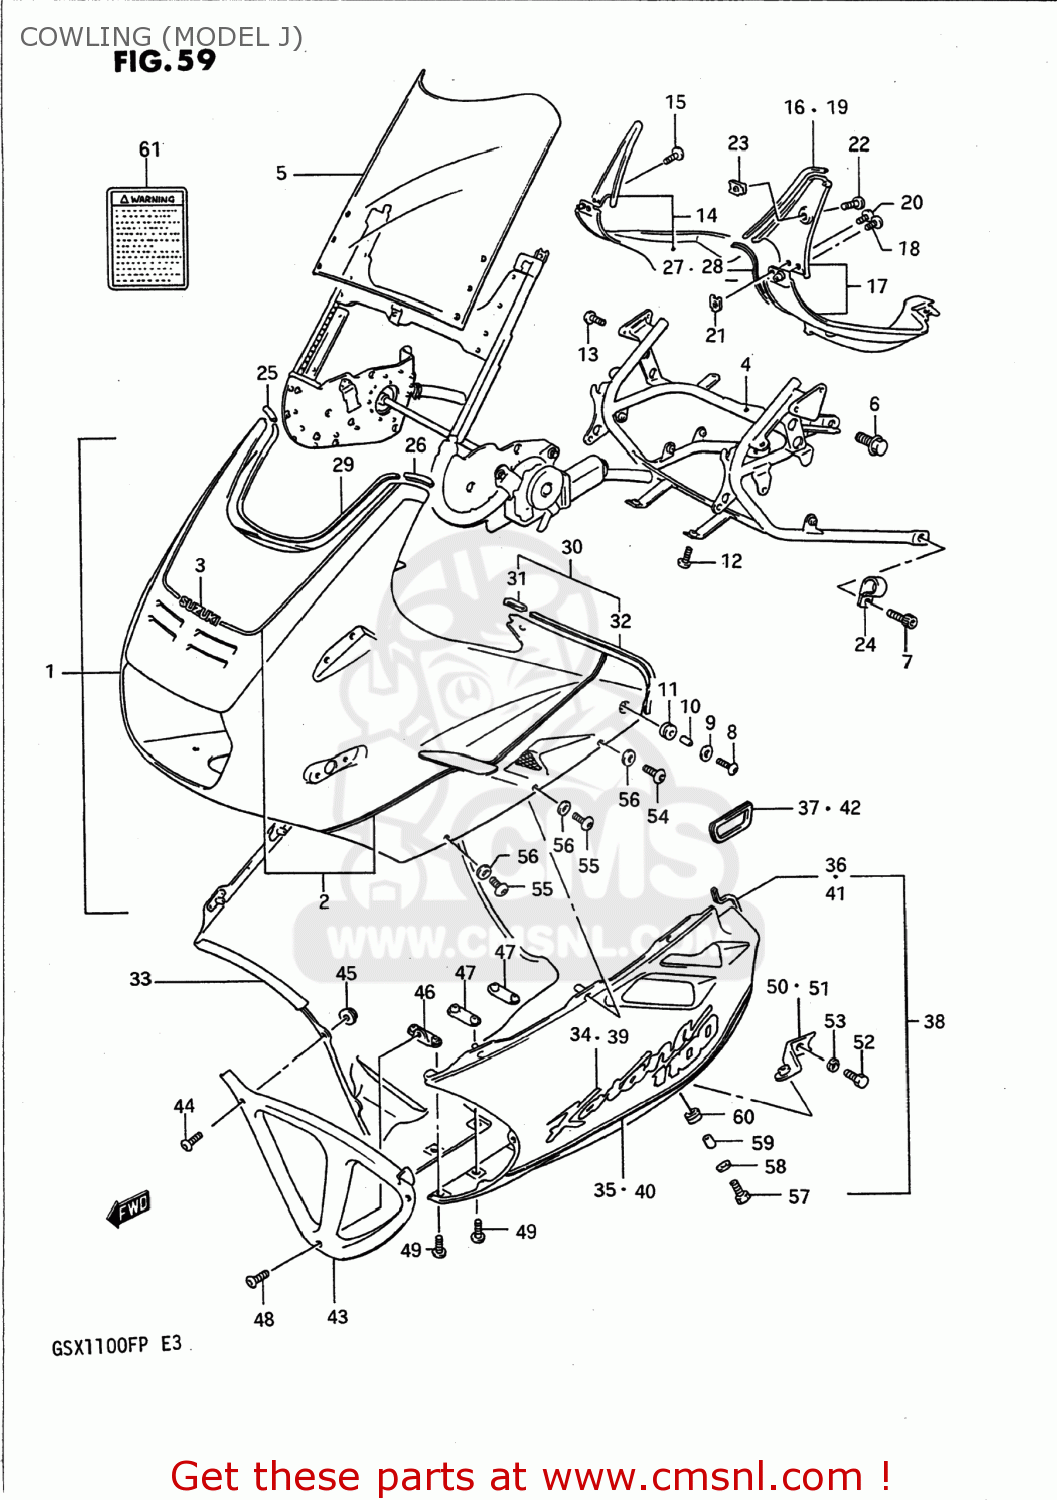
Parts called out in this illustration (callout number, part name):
1	COWLING ASSEMBLY,BODY
2	TAPE SET,COWLING
3	EMBLEM
4	BRACE,COWLING
5	WINDSCREEN
6	BOLT(10X12)
7	BOLT
8	SCREW(6X20)
9	WASHER(6.5X18X1)
10	SPACER
11	CUSHION
12	SCREW(6X16)
13	SCREW 6X12
14	PANEL ASSY,R
15	SCREW
16	MOLDING,COWL.
17	PANEL ASSEMBLY,LEFT
18	SCREW
19	MOLDING,COWL.
20	SCREW, FRONT & REAR
21	NUT
22	SCREW
23	NUT
24	CLAMP
25	CAP,PANEL & COWLING,R
26	CAP,PANEL & COWLING,L
27	MOLDING,COWLING PANEL,R
28	MOLDING,COWLING PANEL
29	MOULDING
30	MOLDING,COWLING BODY SIDE
31	COVER,MOLDING END
32	MOLDING,COWLING BODY SIDE
33	COVER ASSEMBLY,COWLING,LOWER
34	EMBLEM,COWLING,UNDER
35	TAPE,COWLING,RIGHT
36	MOLDING,COWLING,LOWER
37	MOLDING,INLET
38	COVER ASSEMBLY,COWLING,LOWER
39	EMBLEM,COWLING,UNDER
40	TAPE,COWLING
41	MOLDING,COWLING,LOWER
42	MOLDING,INLET
43	COVER,COWLING,LOWER,FRONT
44	SCREW(5X14)
45	NUT
46	BRACE,COWLING LWR COVER
47	BRACE,COWLING LWR COVER RR
48	SCREW(6X12)
49	SCREW(6X16)
50	BRACE,COWLING LWR,R
51	BRACE,COWLING LWR,L
52	BOLT 8X12
53	LOCK WASHER
54	SCREW(6X20)
55	SCREW(6X16)
56	WASHER
57	SCREW(6X20)
58	WASHER(6.5X18X1)
59	SPACER(6.4X9.2X12)
60	CUSHION
61	LABEL (WARNING SCREEN)
